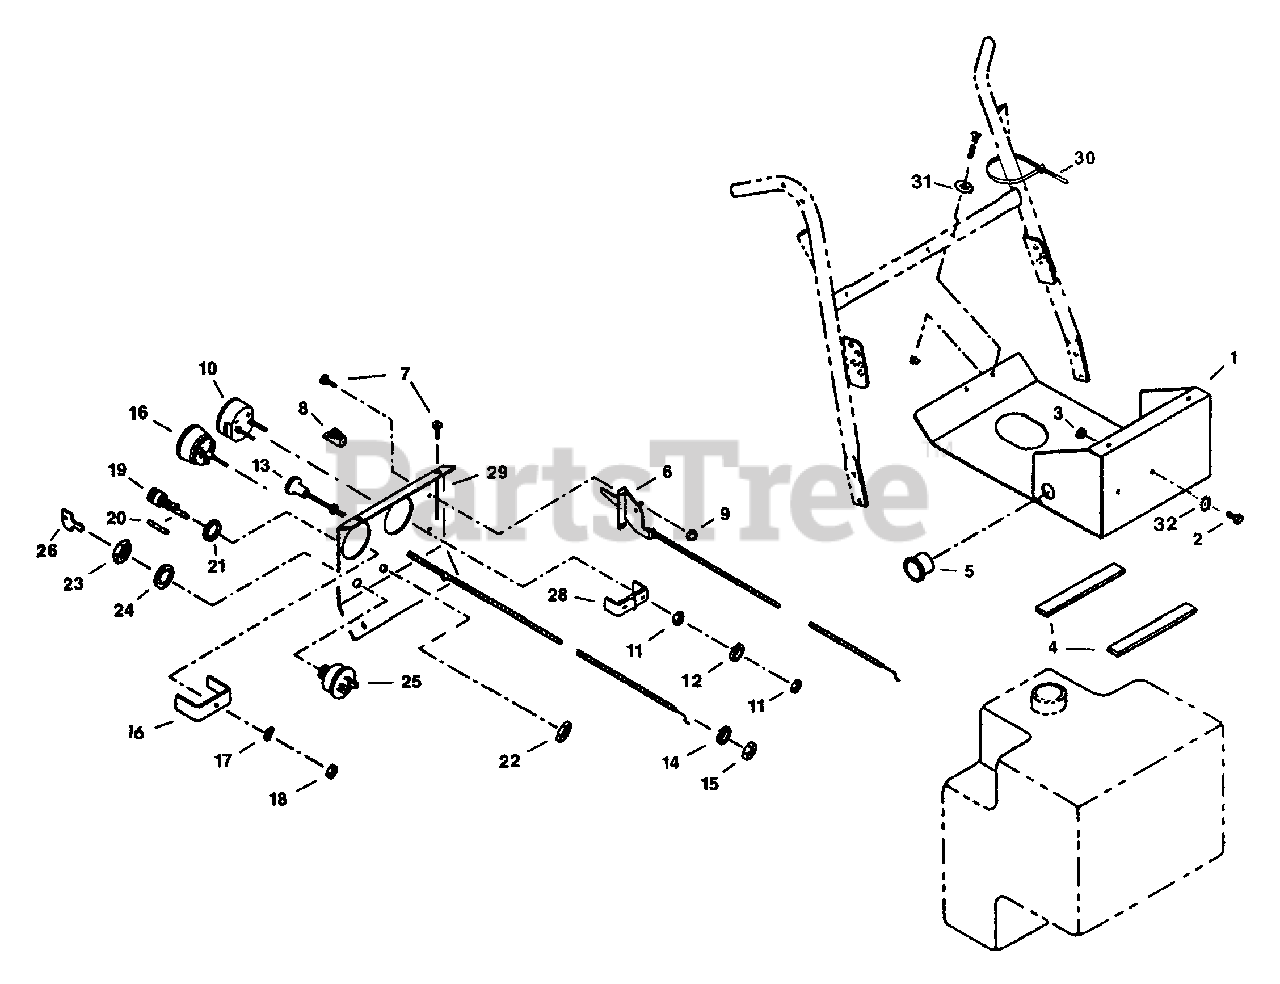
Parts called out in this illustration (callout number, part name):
1	Control Panel-Base Plate w/Decals
2	1/4"-20x1/2" Hex Hd. Cap Screw
3	1/4"-20 Nyloc Hex Nut
4	Control Panel Pad
5	Snap Bushing
6	Throttle Control
7	#10-24x5/8" Pan Hd. Slt. Mach. Screw
8	Throttle Control Knob
9	#10-24 Nyloc Hex Nut
10	Ammeter Complete w/Hdwe.
11	#10-32 Hex Nut
12	#10 Lock Washer
13	Choke Control Complete w/Hdwe.
14	3/8" Lock Washer
15	3/8"-24 Hex Jam Nut
16	Hour Meter Complete w/Hdwe.
17	#10 External Tooth Lock Washer
18	#10-24 Hex Nut
19	Fuse Holder Complete w/Hdwe.
20	1/4"x1-1/4" AGC5 32V Fuse
21	Vinyl Washer
22	Fuse Holder Nut
23	Key Switch Nut
24	5/8" Internal Tooth Lock Washer
25	Key Switch Complete w/Hdwe.
26	Key
28	Ammeter Bracket
29	Control Panel-Face Plate w/Decals
30	Plastic Tie
31	#10 Internal Tooth Lock Washer
32	5/16" External Tooth Lock Washer
